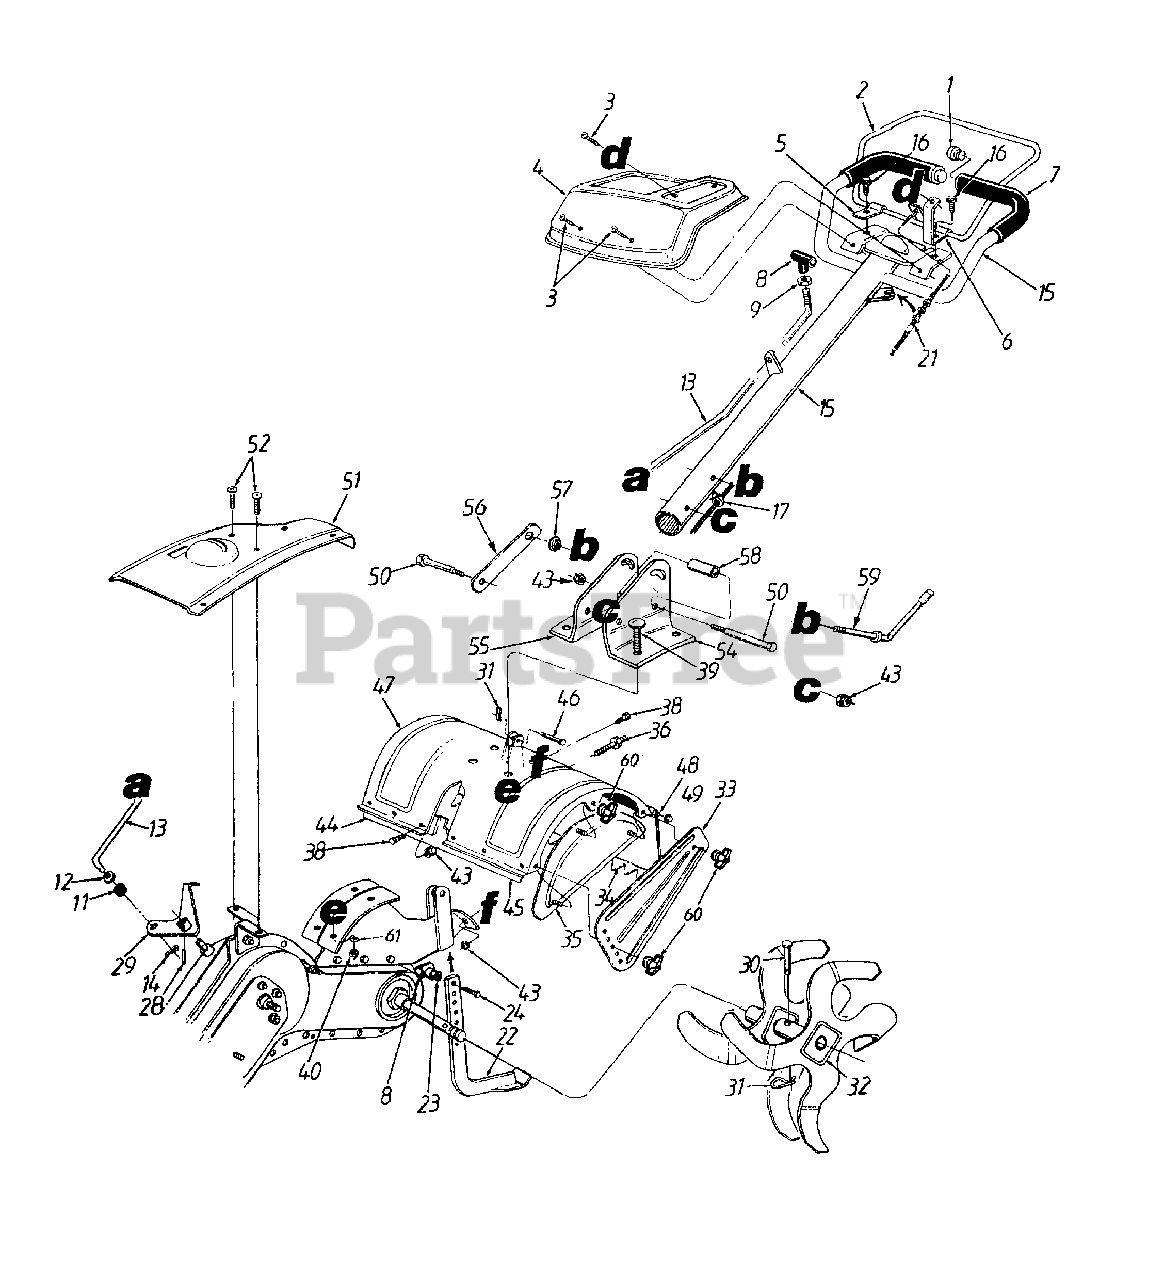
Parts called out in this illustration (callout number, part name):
1	Vinyl End Plug
3	Torx Mach. AB-Tap Scr. 1/4 x .62" Lg.
7	Grip (2 Req'd.)
9	Hex Jam Nut 3/8-16 Thd.
11	Rubber Washer
12	Fl-Wash. .344" I.D. x .6" O.D.
13	Gear Shift Rod
14	Hairpin Clip
17	Cable Clip
21	Clutch Cable
23	Fl-Wash. 3/8" I.D. x 5/8" O.D.
24	Hex Bolt 3/8-16 x 1" Lg."
28	Spiral Pin 3/16" x 1"
31	Hairpin Clip
36	Hex Cap Bolt 5/16-18 x 1.25"
38	Hex Bolt 5/16-18 x .75" Lg.
39	Carriage Bolt 3/8-16 x 1" Lg.
40	Hex Ins. L-Nut 3/8-16 Thd.
43	Hex Flange Top L-Nut 5/16-18 Thd.
46	Clevis Pin .375" Dia.
49	Cap Speed Nut
50	Hex Bolt 5/16-18 x 3" Lg.
57	Hex Flange Nut 3/8-24 Thd.
58	Spacer.322 Dia.
59	Handle Adjustment Crank
60	Knob 5/16-18 Thd.
61	L-Washer 3/8" I.D.
